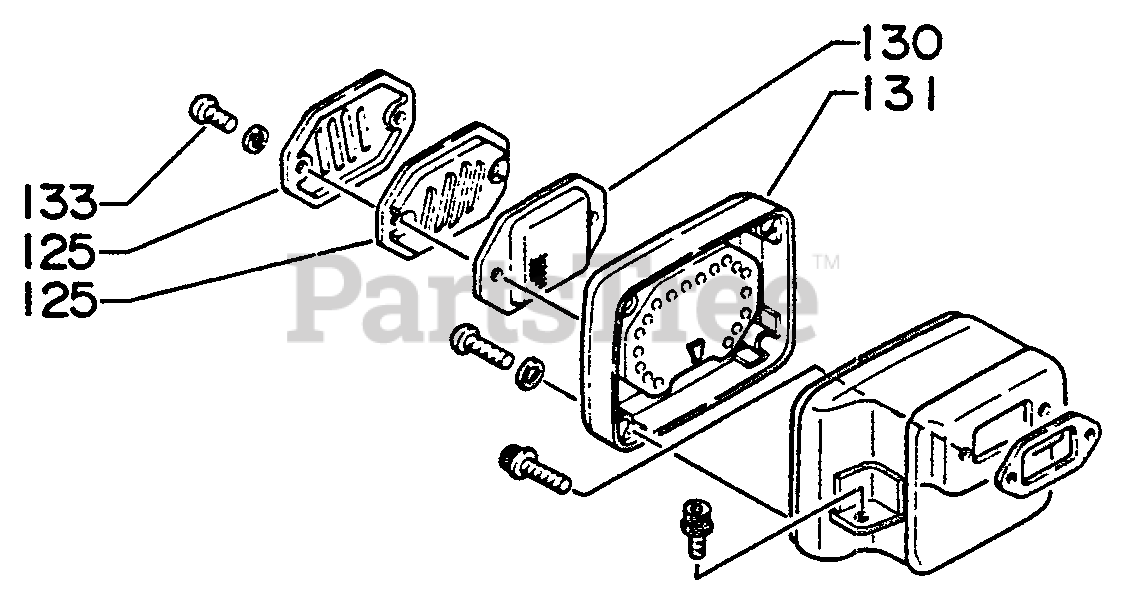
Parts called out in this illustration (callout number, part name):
125	LID, MUFFLER
130	SCREEN, SPARK ARRESTOR
131	MUFFLER
133	SCREW
